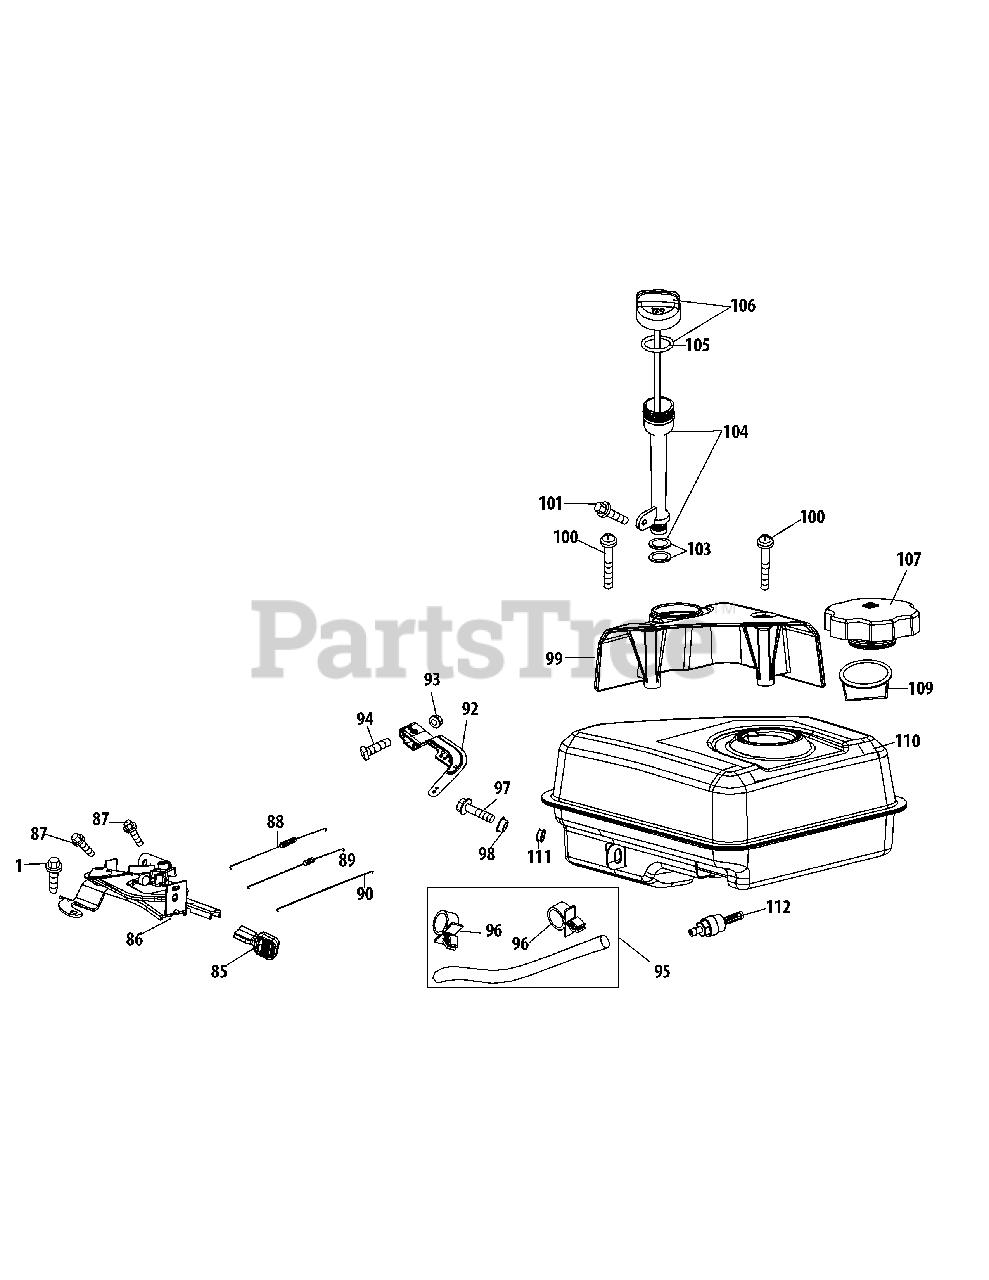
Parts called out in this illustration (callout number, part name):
1	Bolt M6×16
85	Throttle Control Knob
86	Primer Bracket
87	Bolt M6×12
88	Governor Spring
89	Throttle Linkage Spring
90	Throttle Linkage
92	Governor Arm
93	Nut M6
94	Governor Arm Bolt
95	Fuel Line Kit
96	Fuel Hose Clamp
97	Bolt M6×20
98	Isolator Bushing
99	Dipstick Decoration Cover
101	Bolt M6×12
103	Oil Fill Tube O-Ring
104	Oil Fill Tube
105	Dipstick O-Ring
106	Dipstick Guage
107	Fuel Cap Assembly
109	Fuel Filter
111	Rubber Isolation Mount
112	Fuel Tank Nipple
